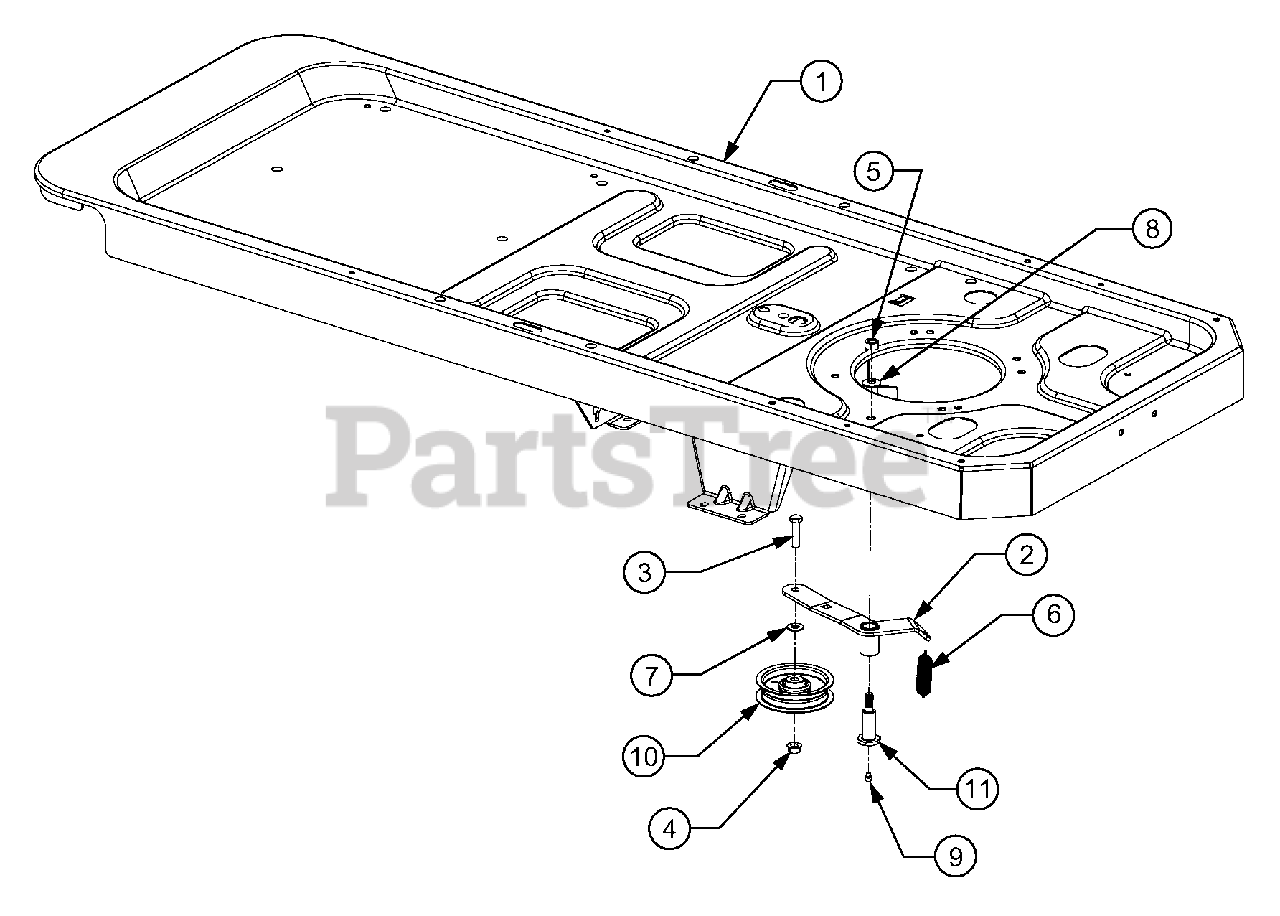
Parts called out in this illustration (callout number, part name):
4	Nut, Hex Flange Lock, 3/-16 GRF
5	Nut, Hex Lock, 7/16-14 GRA
6	Spring, Extension, .75 x 5.06
7	Washer, Flat, .406 x .875 x .059
8	Washer, Flat, .45 x 1.25 x .164 HT
9	Fitting, Lube, 3/16 Drive
10	Pulley, Idler, 3.50 Dia.
11	Screw, Shoulder, .68 x 1.59
